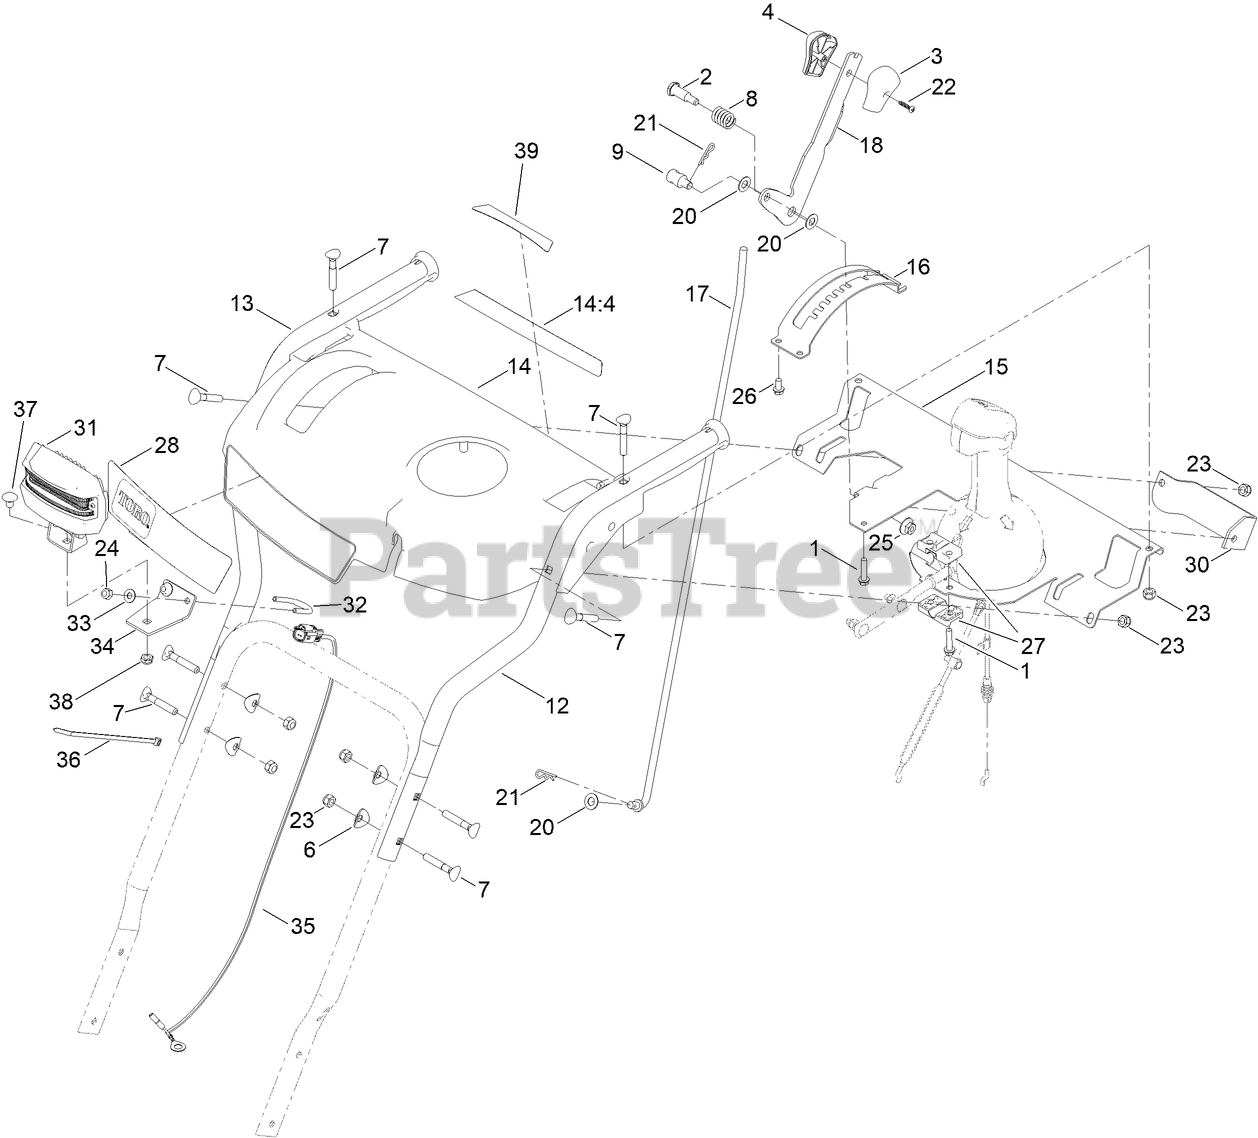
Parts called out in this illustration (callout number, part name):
1	SCREW-PLASTIC,HWH
2	SCREW-SHOULDER, HH
3	KNOB-SHIFT, LH
4	KNOB-SHIFT, RH
6	WASHER-CUP
7	SCREW-HANDLE
8	SPRING-COMPRESSION
9	TRUNNION-ROD
12	HANDLE-UPPER, LH
13	HANDLE-UPPER, RH
14	CONTROL PANEL ASM
14:4	DECAL-SAFETY
15	SUPPORT-PANEL, CONTROL
16	MOUNT-SELECTOR, SPEED
17	ROD-SELECTOR, GEAR
18	SELECTOR-SPEED
20	WASHER-THRUST
21	PIN-HAIR
22	SCREW-PPH
23	NUT-HEX
24	NUT-HEX
25	NUT-HF
26	SCREW-PLASTITE
27	SUPPORT-ROD
28	DECAL-CONSOLE
30	PLATE-SUPPORT, SHIFT
31	LED LIGHT ASM
32	CLAMP-LIGHT
33	WASHER-FLAT
34	BRACKET-LIGHT
35	HARNESS-WIRE
36	TIE-CABLE
37	BOLT-CARR
38	NUT-HEX
39	DECAL - QUICK STICK
